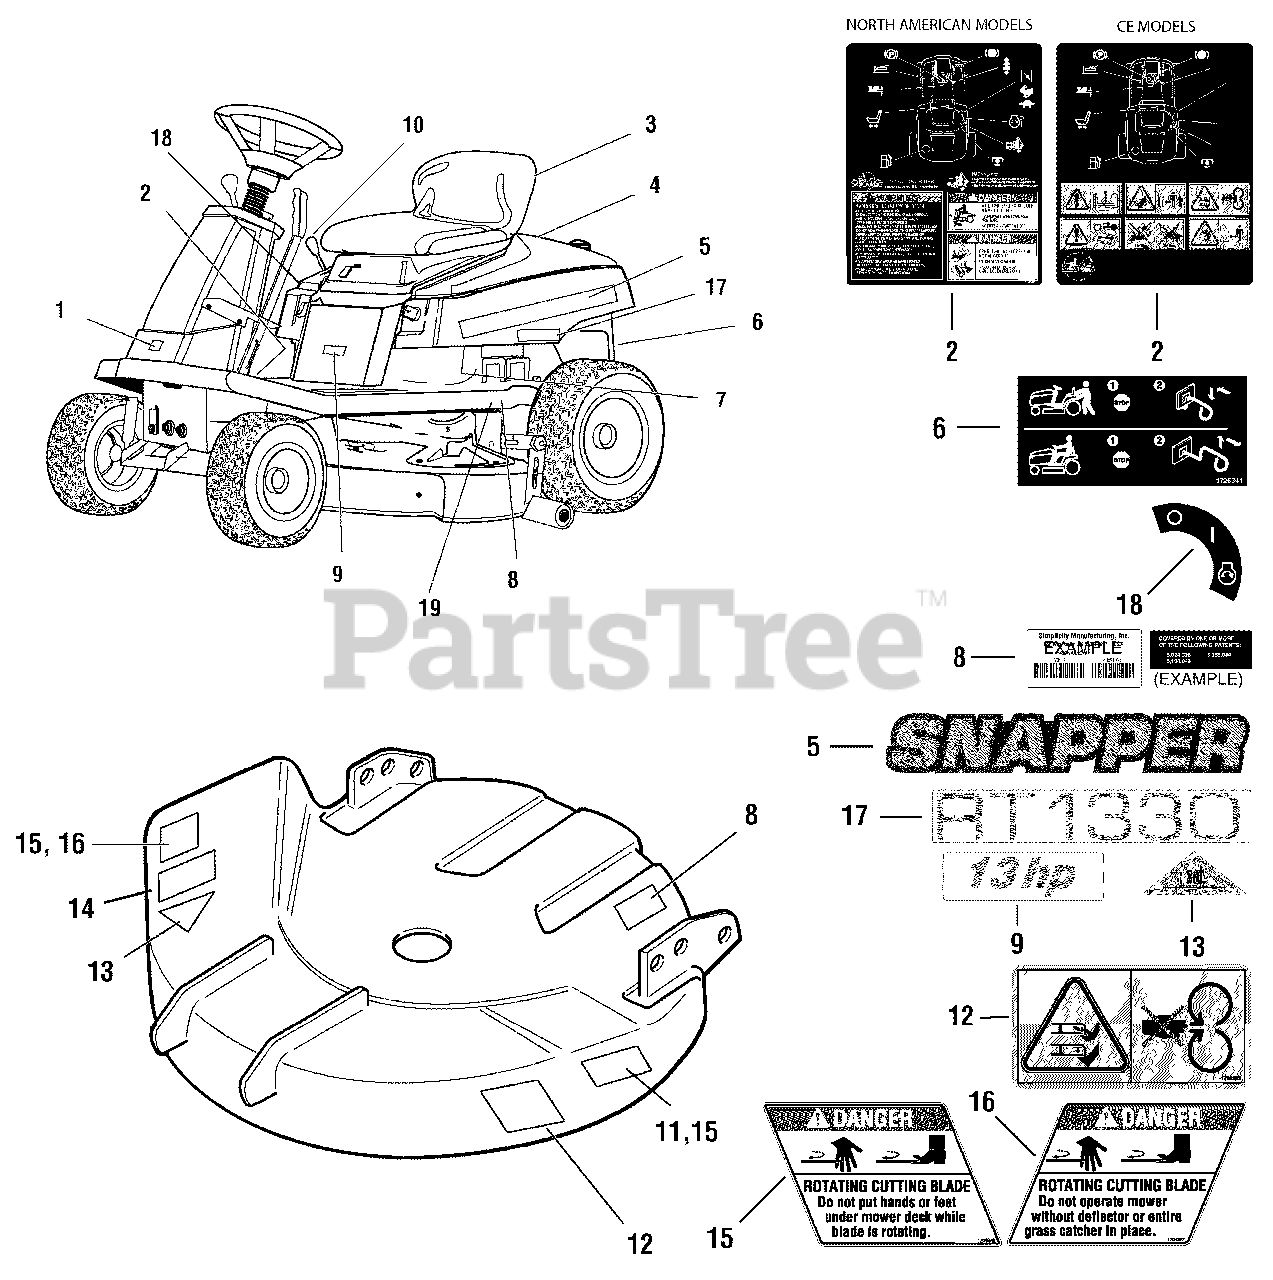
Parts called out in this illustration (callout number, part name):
1	* DECAL, C E, (Export Only)
2	DECAL, Operating Instruction, English
2	DECAL, Operating Instructions, Export
3	DECAL, USA (Seat Back) (CE/Export Only)
4	DECAL, Belt & Blade Replacement
5	DECAL, Snapper Logo
6	DECAL, Transmission Release (Hydro models only)
7	DECAL, Touch-up Pain, Red & Gray
8	* I.D. PLATE (Not Serviced)
9	DECAL, 13 HP
10	DECAL, Throttle / Choke
10	DECAL, Throttle
11	DECAL, Free Floating Mower
12	DECAL, Danger, Rotating Cutting Blade
13	* DECAL, OPEI, (Not Serviced)
14	DECAL, Cutting Width - 30 , Silver on Black
15	DECAL, Danger, Rotating Blades (CE/Export Only)
16	DECAL, Danger, Chute In Place
17	DECAL, Model RT1330
18	DECAL, Ignition Switch
19	* DECAL, Decibel, Power Mass (CE/Export Only)
